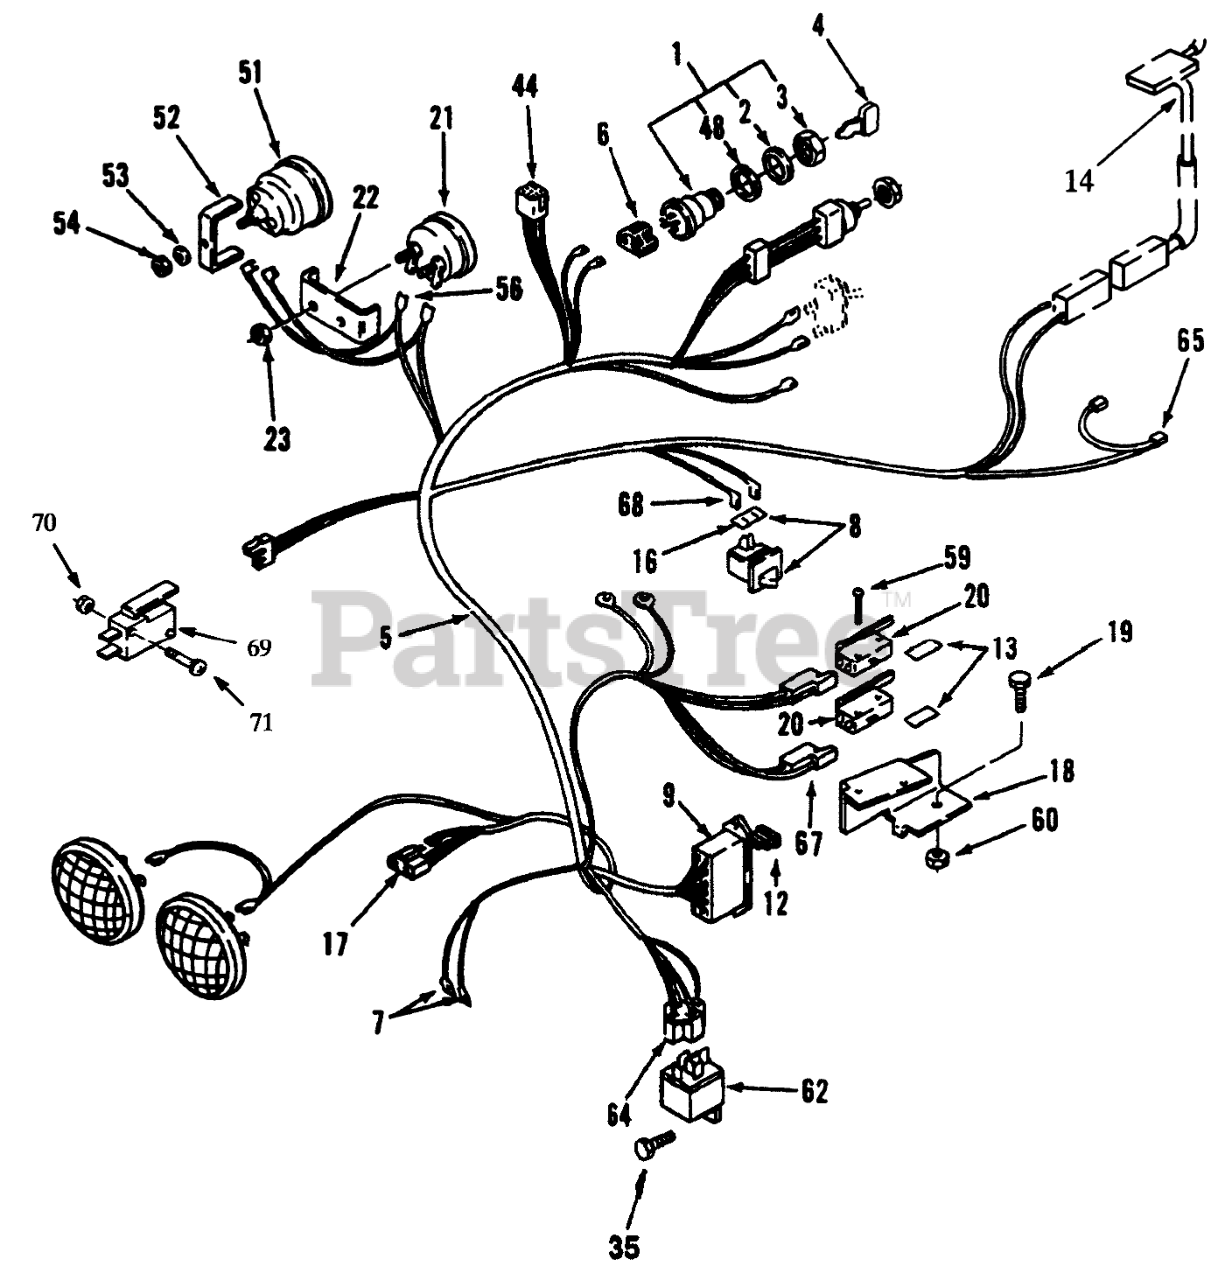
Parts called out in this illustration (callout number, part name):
1	IGNITION SWITCH ASM
2	LOCKWASHER
4	KEY-IGNITION
4	Boot
5	Wiring Harness (Incl. Ref. #6, 7, 9, 17, 44, 65 & 68)
6	CONNECTOR BODY ELECT
7	TERMINAL 10
8	Switch-Clutch Interlock, (Incl. Ref. #16)
9	FUSE-HOLDER 4 WAY
12	FUSE-BLADE, 15 AMP
13	BARRIER - SWITCH
14	SWITCH-SEAT
16	SHIELD-DIRT SPST
17	5-CONTACT CONN BODY
18	BRACKET-SWITCH
19	SCREW-HWH
20	SWITCH
21	VOLTMETER
22	CLAMP-MOUNTING
23	HEX NUT 10-32 E.S.
35	SCREW-PAN
48	WASHER
51	Meter-Hour (Incl. Ref. #52-54)
52	CLAMP-HOUR METER
53	Lockwasher
54	Hex Nut
59	SCREW-PHL 4-40X1 1/4
60	NUT-HEX
62	RELAY
64	TERMINAL 10
65	Sur-Plug
68	Terminal
69	SWITCH
70	NUT-HEX
71	Screw
